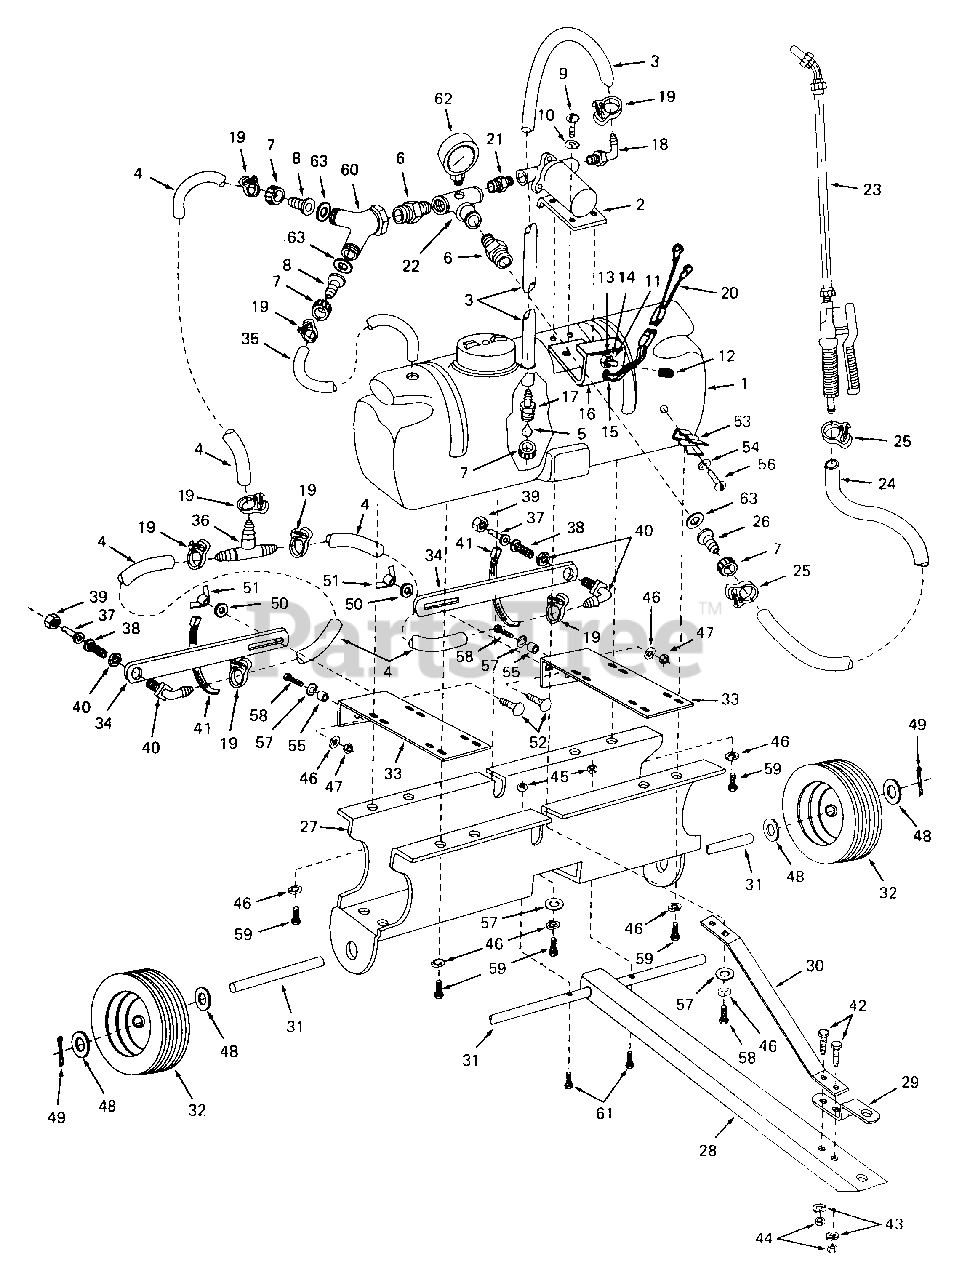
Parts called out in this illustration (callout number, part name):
1	Tank w/Cap, 25 Gallon
2	Pump, Motor/w
3	Hose, 1/2 ID X 24" Lg
4	Hose, 1/2 ID X 20" Lg
6	Adapter, 1/2 NPT X Hose
7	Nut, Swivel 3/4 Hose
8	Barb, 1/2 Hose
9	Screw, Pan Hd, #10-24 X 1 Lg
10	Washer, Flat
11	Switch, On-Off
12	Boot, Rubber
13	Plate, Switch
14	Nut, Switch
16	Bracket, Switch Mtg
17	Adapter, 3/4 Hose X 1/2 Barb
18	Elbow, 3/8 NPT X 1/2 Barb
19	Clamp, 1/2
20	Harness, Battery
21	Nipple, 1/2 X 3/8 Nylon
23	Gun, Spray
24	Hose, 3/8 ID X 12'-6" Lg
25	Clamp, 3/8
26	Barb, 3/8 Hose
30	Brace, Hitch
34	Bar, Boom
35	Hose, 1/2 ID X 14" Lg
37	Nozzle, SS Floodjet
38	Strainer, Screen Type
39	Nut, Screen Body
41	Tie, Cable
42	Screw, Hex Cap, 3/8-16 X 1.25 Lg GR5
43	Washer, Lock, 3/8
44	Nut, Hex Center Lock, 3/8-16
45	Nut, Hex Center Lock, 1/4-20
46	Washer, Lock, 5/16
47	Nut, Hex, 5/16-18
48	Washer, Flat, .781 X 1.59 X .065 Thk
49	Pin, Cotter, 1/8 X 1.50 Lg
50	Washer, Flat, 1/4
51	Nut, Wing Lock, 1/4-20
52	Bolt, Carriage, 1/4 X .75 Lg
53	Clip, Hose
54	Washer, Lock, #10
55	Bushing, Pivot
56	Screw, Slot Hd, #10-24 X .50 Lg
57	Washer, 5/16
58	Screw, Hex Cap, 5/16-18 X .75 Lg
59	Screw, Hex Cap, 5/16-18 X .50 Lg
60	Connector, Y
61	Screw, Hex Cap, 1/4-20 X 1.50 Lg
62	Gauge, Pressure, 100 PSI
63	Gasket, 3/4 Hose
